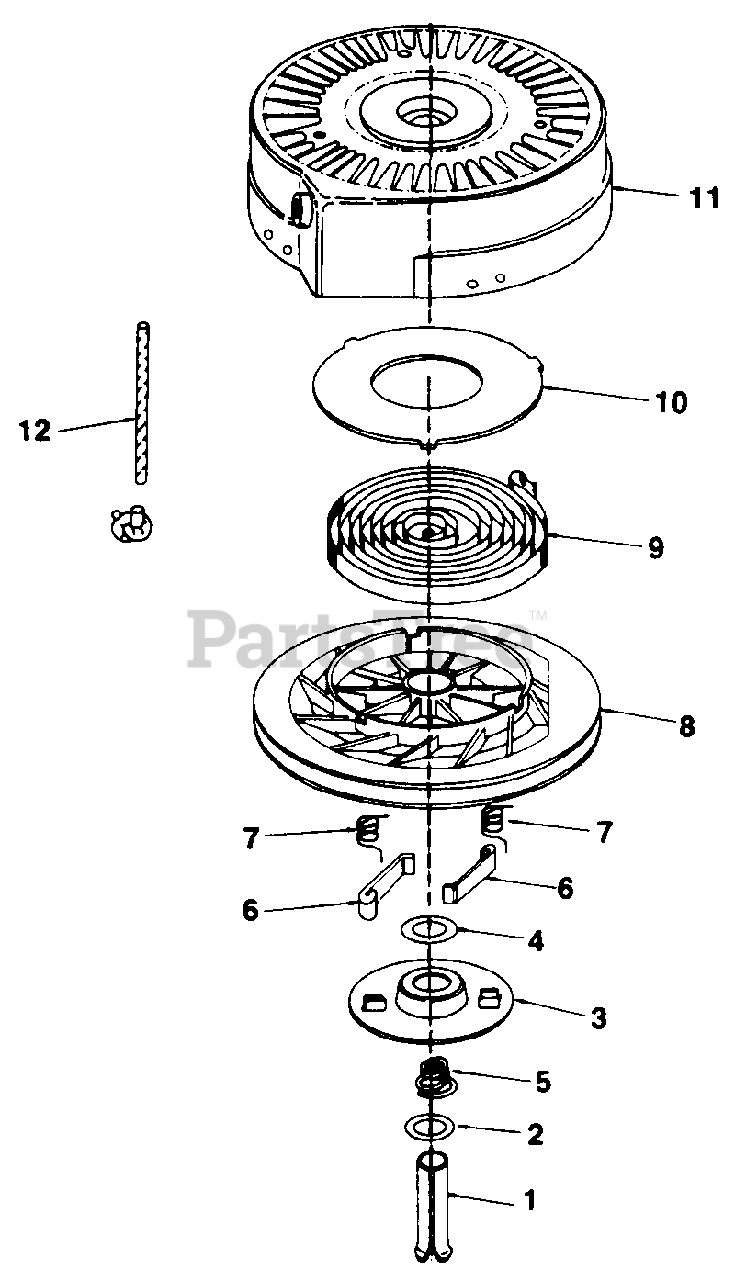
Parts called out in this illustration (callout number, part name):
1	Pin, Spring
5	Spring, Brake
6	Dog, Starter
7	Spring, Dog
8	Pulley
9	Spring, Rewind
10	Cover, Spring
11	Housing Ass'y., Starter
12	Rope, Starter (Length 98" & 9/64" Dia.)
